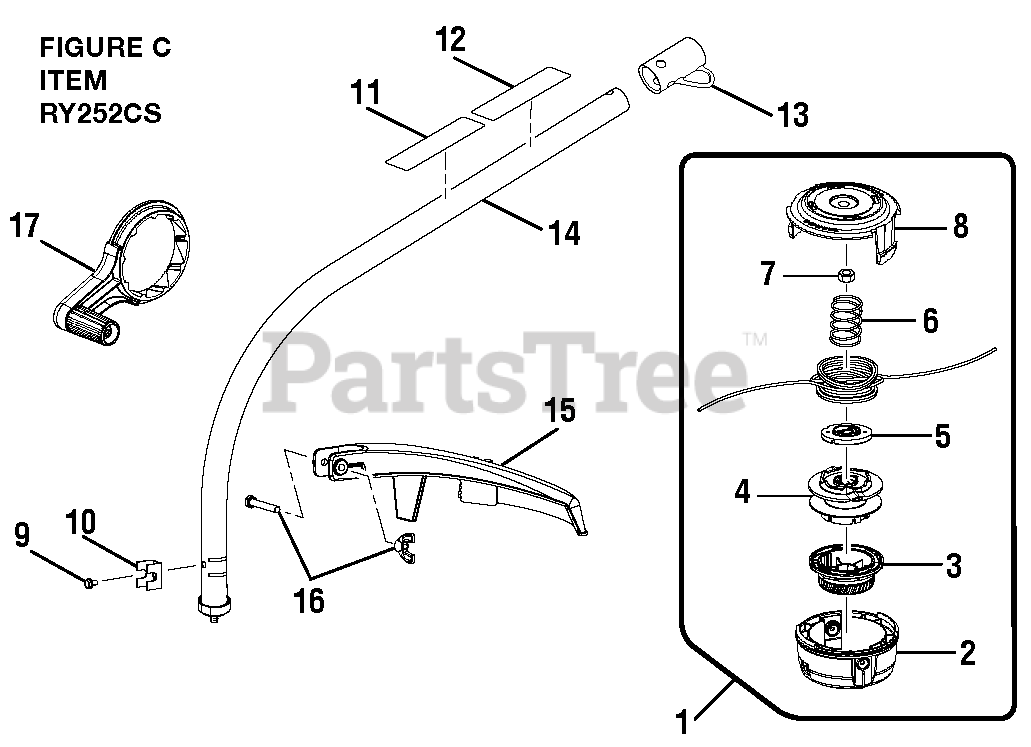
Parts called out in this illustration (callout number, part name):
1	Trimmer Head Assembly (.095)
2	Lower Housing
3	Bump Knob (Green)
5	String Guide
6	Compression Spring
7	Hex Nut (M8)
8	Upper Housing
9	Screw (#10-32 x 3/8 in., Hex Washer Hd. S.T.)
11	Expand-it Label
12	Warning Icon Label
13	Storage Hanger Cap
14	Curved Shaft Assembly
15	Grass Deflector Assembly
16	Fastener Kit
17	Crank Handle Assembly
